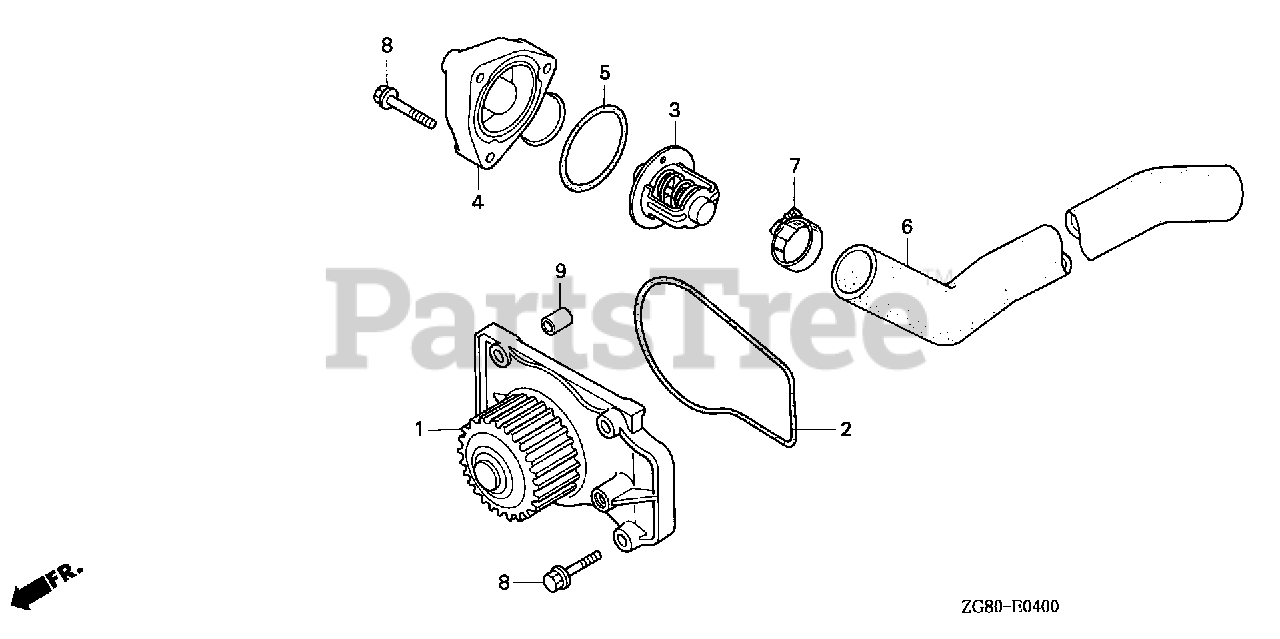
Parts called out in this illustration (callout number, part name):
1	WATER PUMP
2	O-RING, WATER PUMP
3	THERMOSTAT
4	COVER, THERMOSTAT
5	O-RING, THERMOSTAT COVER
6	HOSE B, WATER (LOWER)
7	BAND, WATER HOSE
8	BOLT, FLANGE (6X32) (CT200)
9	PIN, DOWEL (8X14)
